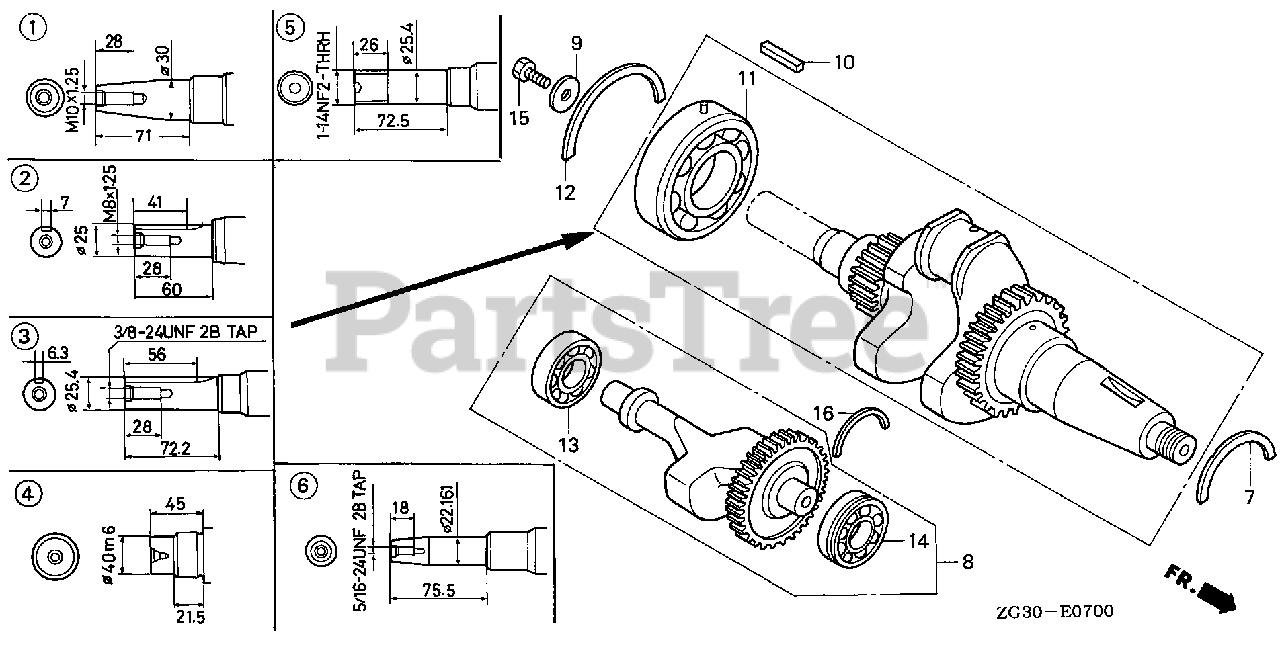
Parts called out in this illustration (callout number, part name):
3	CRANKSHAFT
7	BEARING A, CRANKSHAFT THRUST (BLUE)
8	WEIGHT, BALANCER
10	KEY (6.3X6.3X43)
11	BEARING, SPECIAL (6308) (NTN)
12	SET-RING (90MM)
13	BEARING B, SPECIAL BALL (6304)
14	BEARING C, SPECIAL BALL (6304)
16	SET-RING (520) (NOT AVAILABLE)
